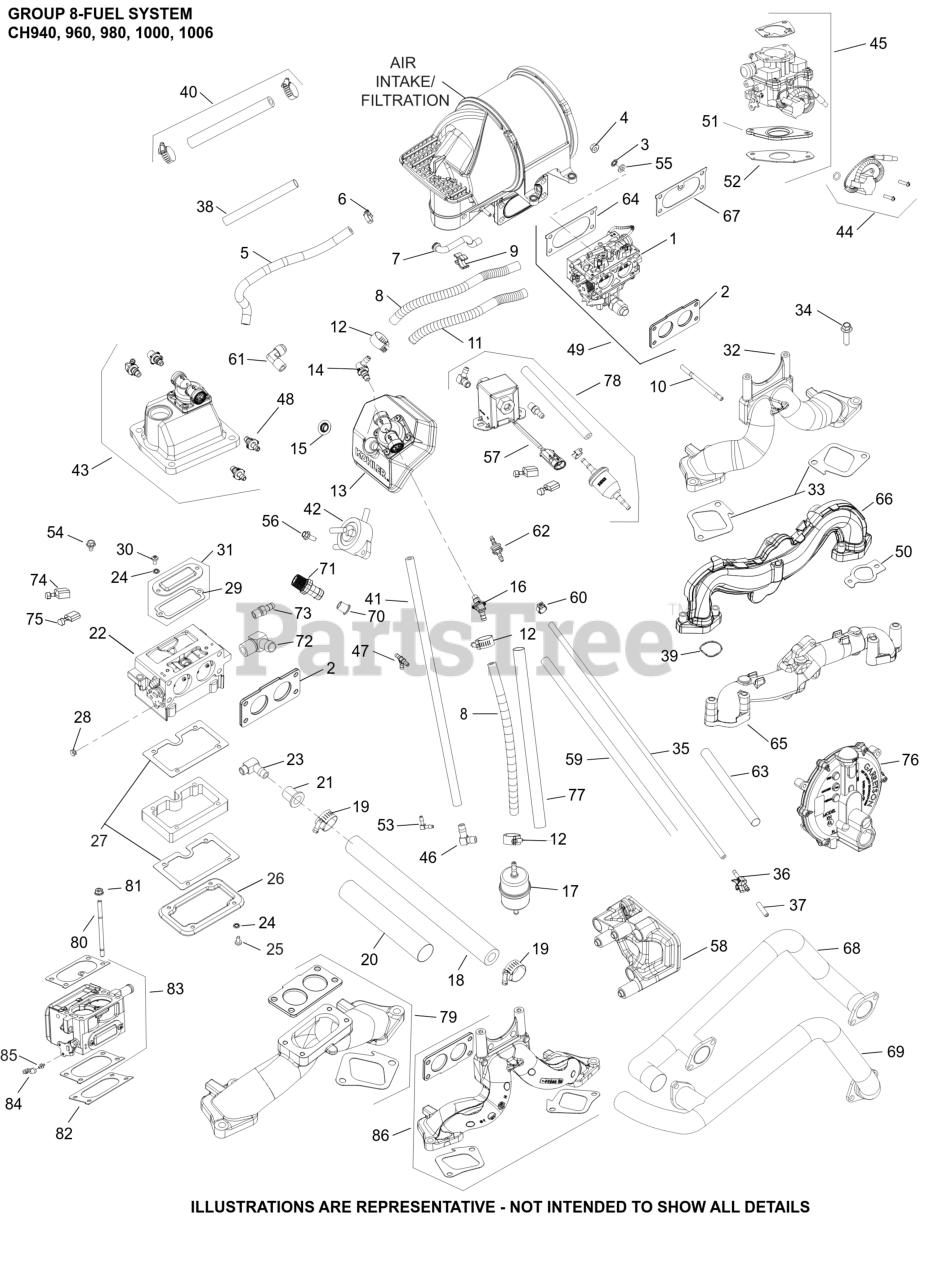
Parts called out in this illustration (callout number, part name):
33	GASKET, INTAKE MANIFOLD
34	SCREW, FLG M8X1.25X30
79	KIT, INTAKE MANIFOLD
81	NUT, HEX FLANGE
82	GASKET, MIXER
84	CUP, BALL JOINT
85	SCREW, CUP JOINT GOVERNOR
NI	PLUG, CAP 1/4 INCH
NI	KIT, CARBURETOR
